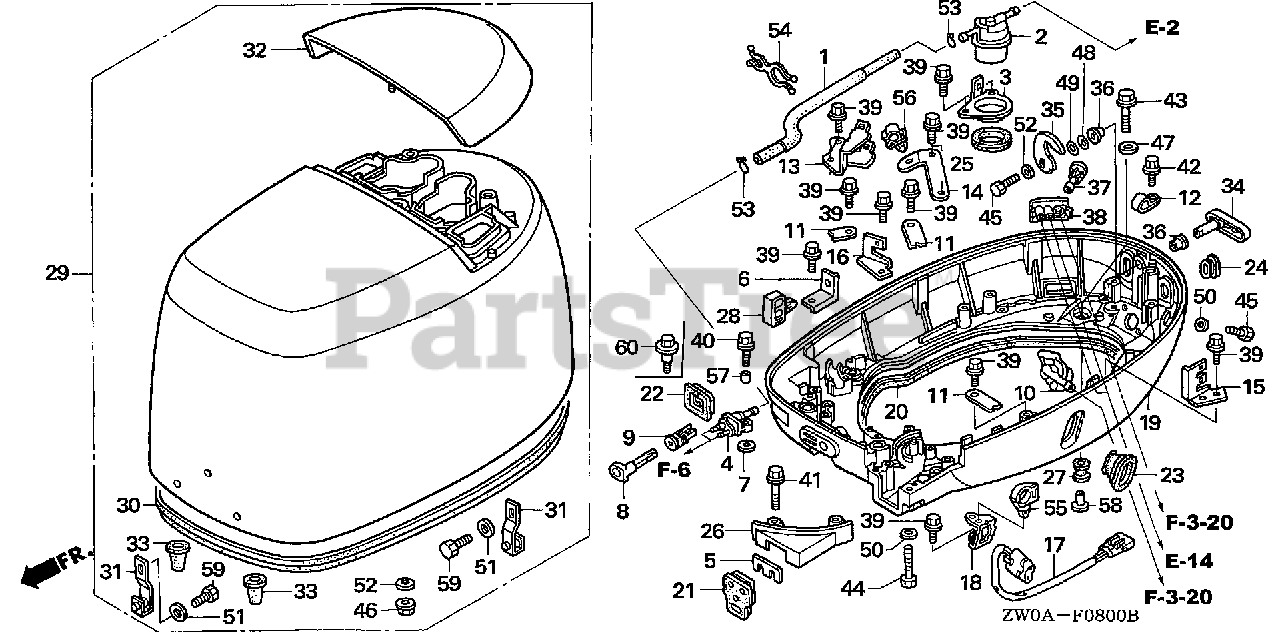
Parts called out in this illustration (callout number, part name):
1	TUBE, FUEL
2	FILTER, FUEL (TOYO ROKI)
3	STAY, FUEL STRAINER
4	CONNECTOR ASSY., FUEL (B)
5	PLATE, REMOTE CONTROL CABLE
6	HOLDER, THROTTLE CABLE
7	WASHER, PIVOT
8	KNOB, CHOKE
9	GUIDE, CHOKE KNOB
10	JOINT, WATER INLET
11	PLATE, SHIFT SHAFT
12	CLAMP, IGNITION WIRE
13	BRACKET, CONNECTOR
14	BRACKET, CLIP A
15	BRACKET, CLIP B
16	BRACKET, HARNESS CLIP
17	SWITCH ASSY., POWER TRIM-TILT
18	STAY, POWER TILT SWITCH
19	CASE, ENGINE (LOWER) *NH282MU* (OYSTER SILVER METALLIC-U)
20	SEAL, CASE (LOWER)
21	GROMMET, CASE (LOWER) (A)
22	GROMMET, CASE (LOWER) (B)
23	GROMMET, CASE (LOWER) (G)
24	GROMMET, CASE (LOWER)
25	GROMMET, FUEL STRAINER
26	CASE, SEPARATE *NH282MU* (OYSTER SILVER METALLIC-U)
27	RUBBER, FR. CARRIER CUSHION
28	CLIP, RETURN PIPE (6MM)
29	COVER ASSY., ENGINE *NH282MU* (OYSTER SILVER METALLIC-U)
30	SEAL, ENGINE COVER
31	HOOK, ENGINE COVER
32	HANDLE, TILT *NH282MU* (OYSTER SILVER METALLIC-U)
33	DAMPER, HOOK
34	LEVER, COVER LOCK *NH282MU* (OYSTER SILVER METALLIC-U)
35	HOOK, COVER LOCK
36	BUSH, COVER LOCK
37	GROMMET, WATER CHECK
38	GROMMET, WATER CHECK
39	BOLT, FLANGE (6X12)
40	BOLT, FLANGE (6X20)
41	BOLT, FLANGE (6X28) (CT200)
42	BOLT, FLANGE (5X10)
43	BOLT, FLANGE (8X35)
43	BOLT-WASHER (8X35)
44	BOLT, HEX. (6X35)
45	BOLT, HEX. (6X16)
46	NUT, U (6MM)
47	WASHER, PLAIN (8MM)
48	WASHER (14MM)
49	WASHER, WAVE (14MM)
50	WASHER, PLAIN (6MM)
51	WASHER, PLAIN (8MM)
52	WASHER (6MM)
53	CLIP, TUBE (B12)
54	CLIP, PURSE LOCK
55	CLAMP, HARNESS
56	CLIP, CABLE
57	COLLAR, DISTANCE (6MM)
58	COLLAR (8.3X14.5)
58	COLLAR (8.5X14.5)
59	BOLT, HEX. (8X16)
59	CLIP, TUBE (B12)
60	BOLT, SPECIAL (6X22) (CT200)
